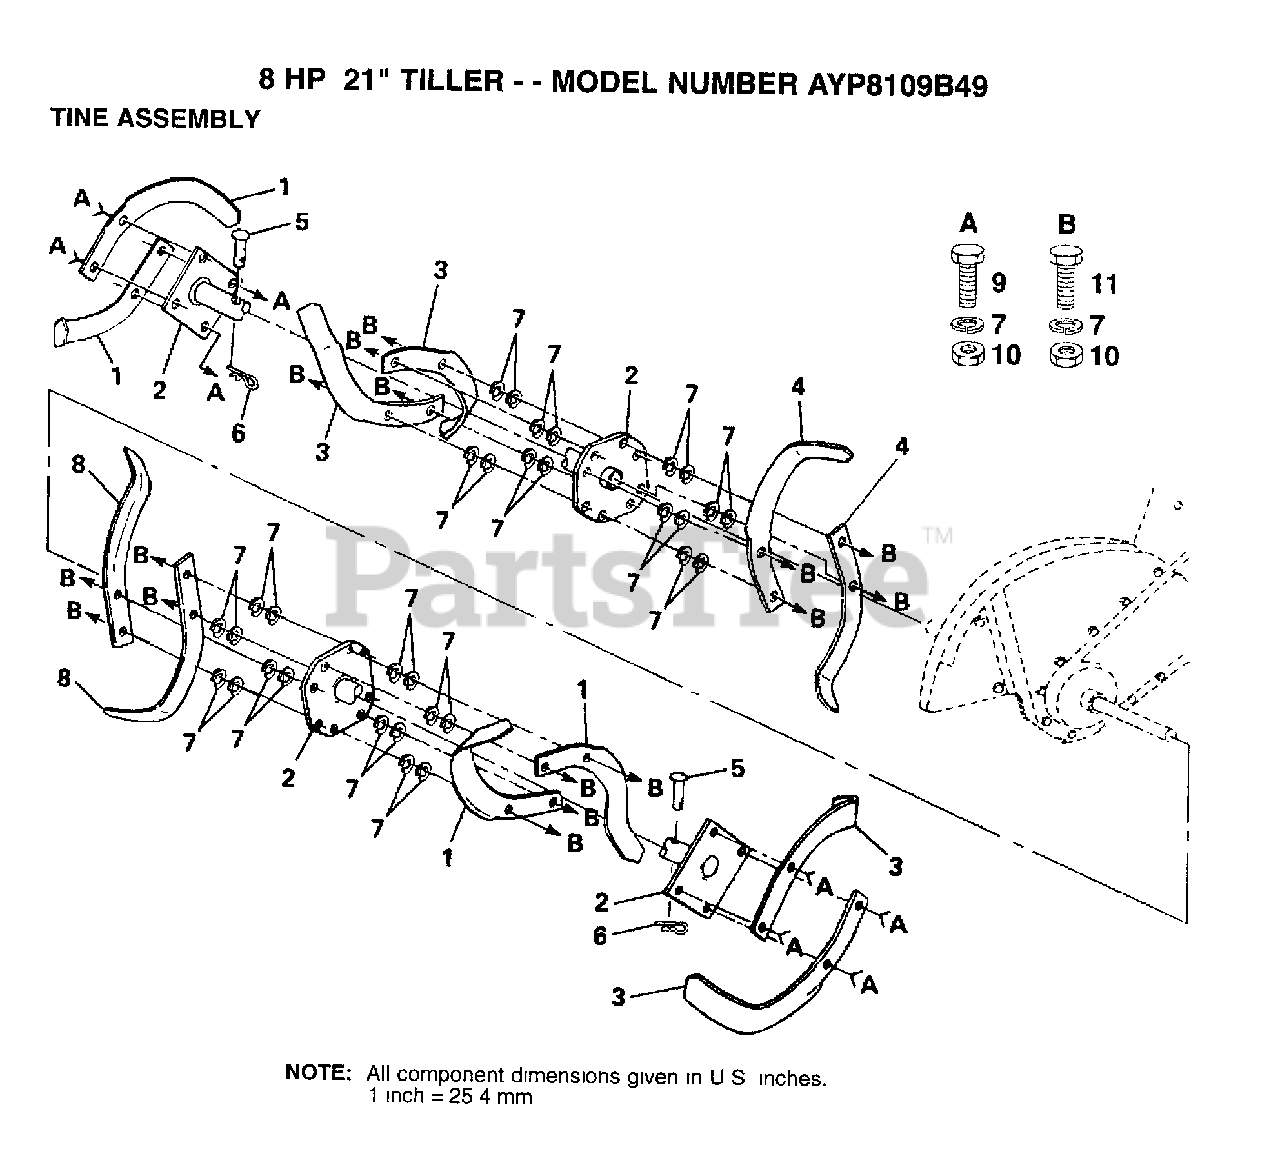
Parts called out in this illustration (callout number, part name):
2	TINE ASSY CRT
4	TINE.LH.CRT
5	RIVET.PAN HD.1.75
6	RETAINER.SPRING
7	LOCKWASHER
8	TINE RH CRT
9	BOLT
11	BOLT.3/8-24X1-1/2
